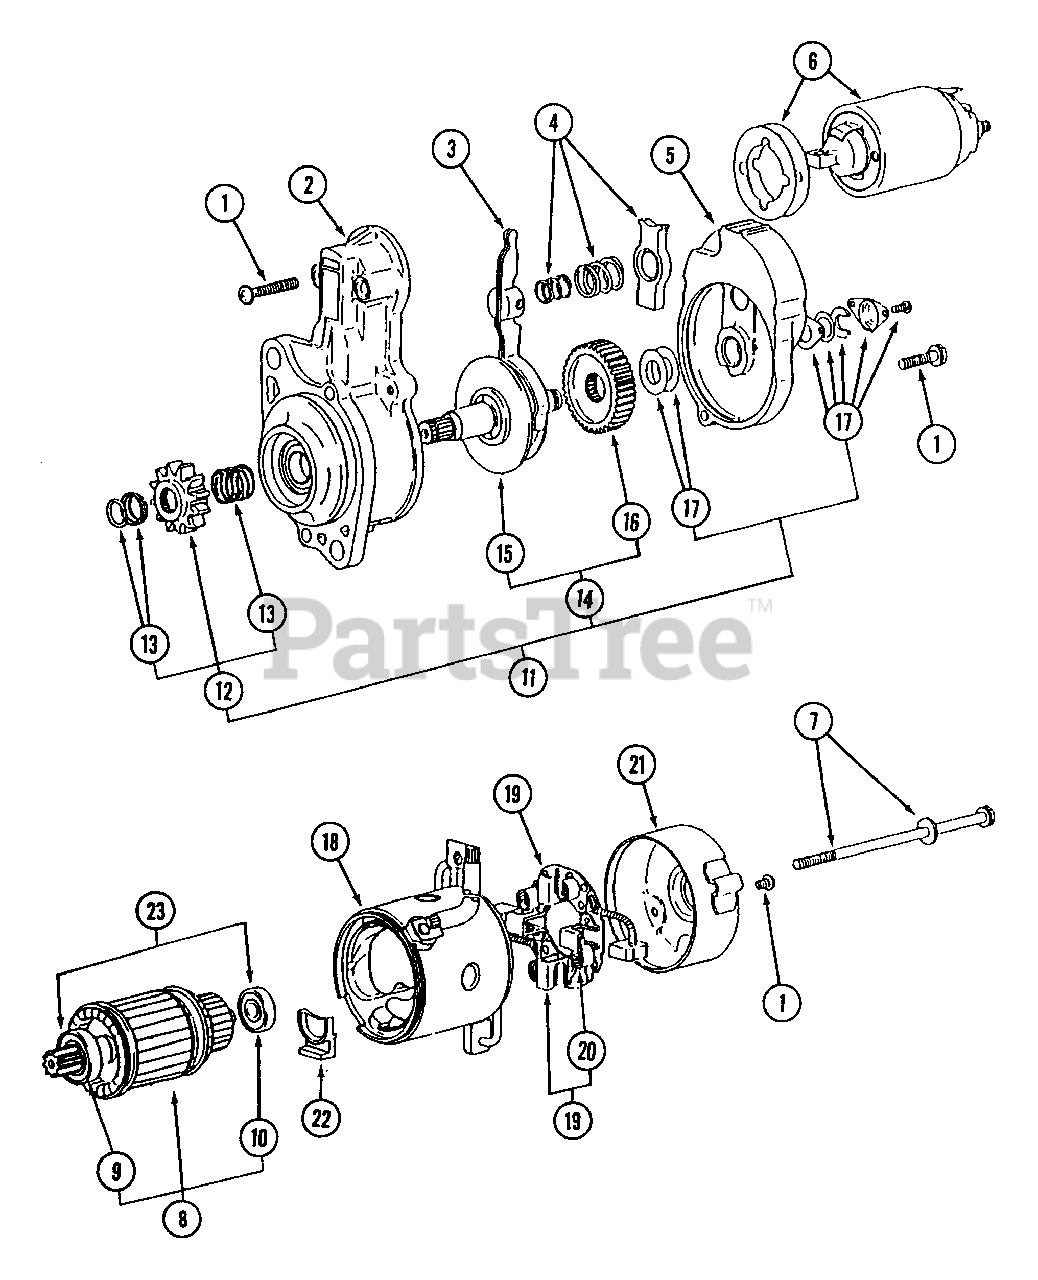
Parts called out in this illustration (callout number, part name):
1	Screw Set
2	Bracket Ass'y., Front
3	Lever Ass'y.
5	Bracket Ass'y., Center
6	Switch Ass'y.
8	Armature Set
9	Bearing, Front
10	Bearing, Rear
11	Shaft Ass'y., Clutch Set
13	Stopper Set
15	Shaft Ass'y., Pinion
18	Yoke Ass'y.
19	Holder Ass'y., Brush
20	Spring, Brush
21	Bracket Ass'y., Rear
23	Service Kit, Starter Bearing
